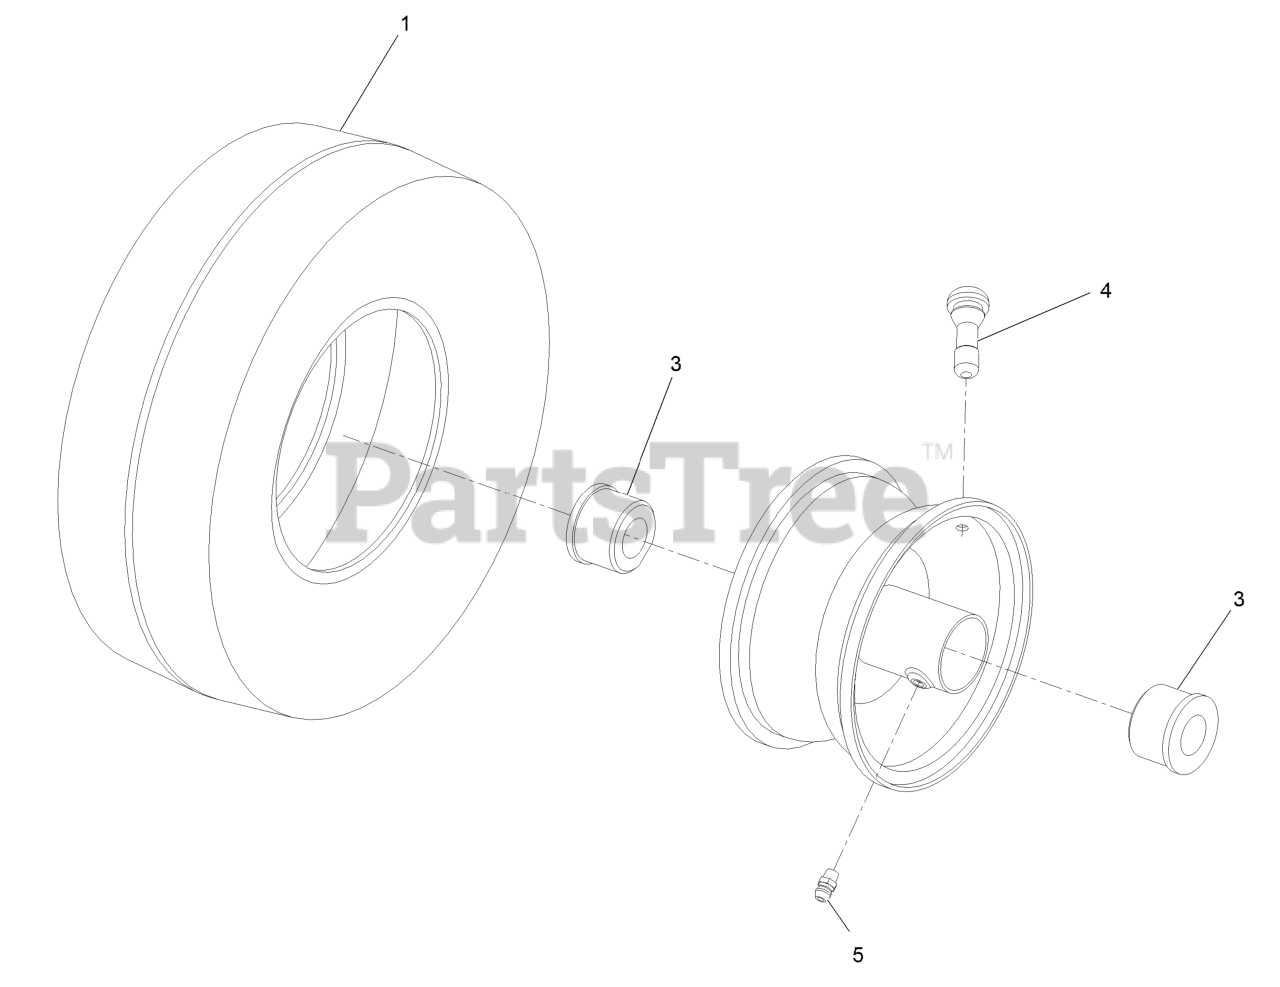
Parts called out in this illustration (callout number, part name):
3	BUSHING-FLANGE
4	Stem-Valve
5	FITTING-GREASE
